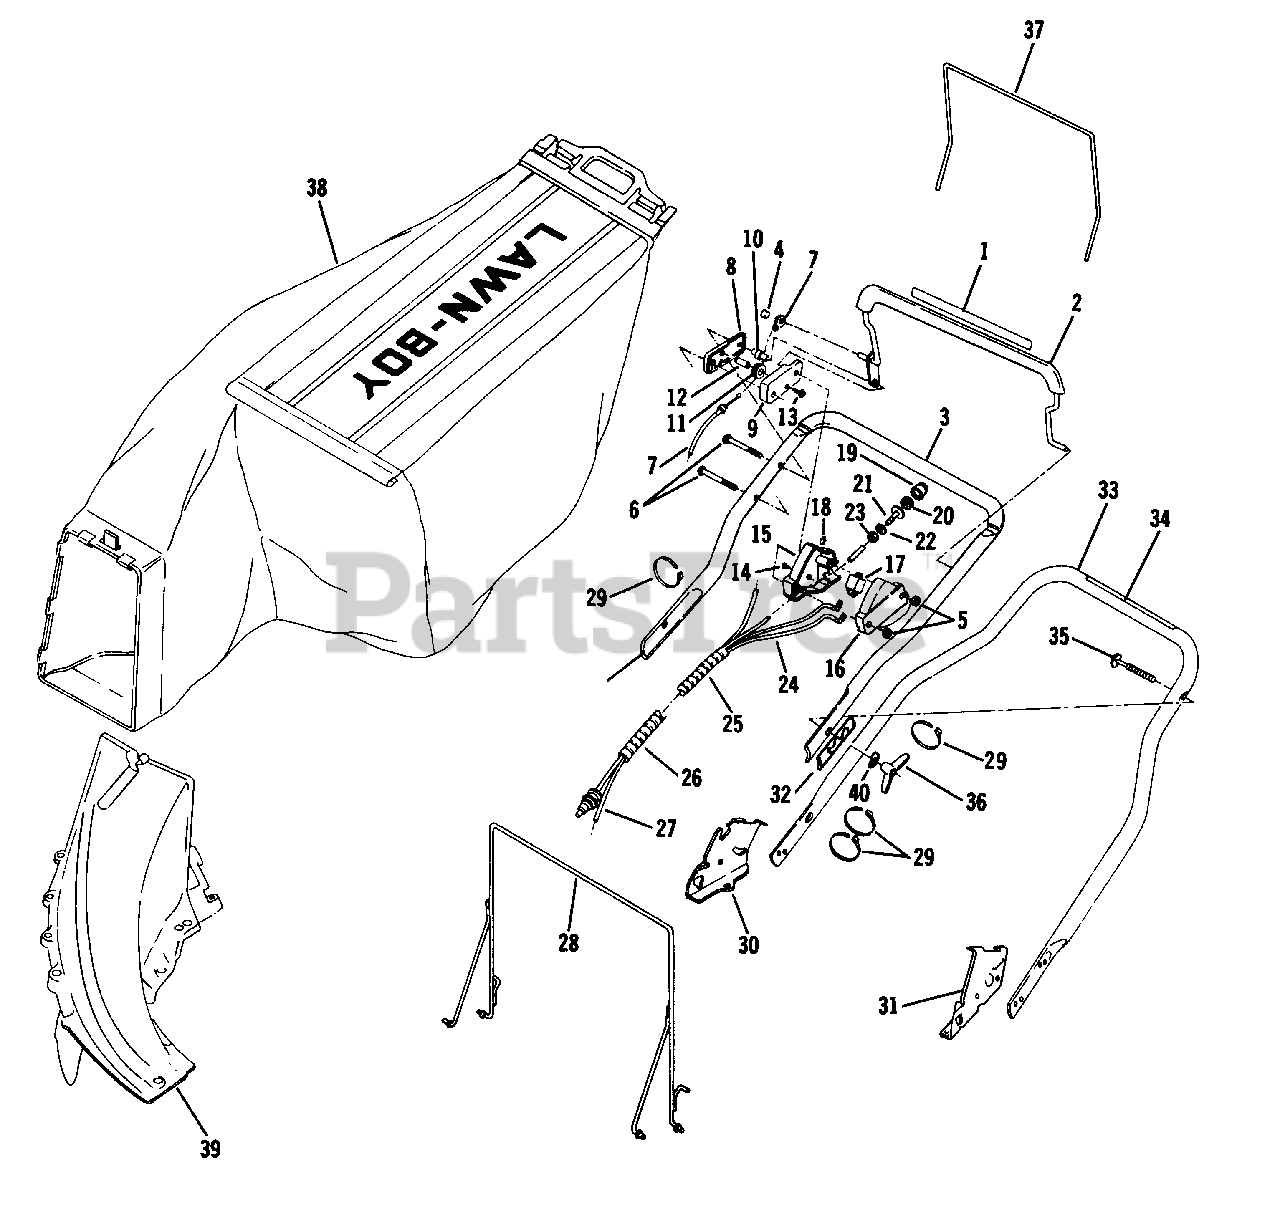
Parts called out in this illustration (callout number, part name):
1	Decal-Blade Control
2	Control Lever Assembly
3	Top Handle and Grip Assembly
4	Pushnut
5	Nut-Hex-Centerlock
6	Screw
7	Control Cable Assembly
8	Control Case-Outer
9	Control Case-Inner
10	Column
11	Pulley
12	Pin
13	Screw
14	Screw
15	Console-R.H.
16	Console-L.H.
17	Switch Assembly
18	Decal
19	Primer Bulb
20	Filter
21	Primer Base
22	Washer
23	Locknut
24	Wire Harness Assembly
25	Spiral Tubing
26	Spiral Tubing
27	Tubing
28	Hanger Assembly-Front
29	Tie Strap
30	Handle Bracket-R.H.
31	Handle Bracket-L.H.
32	Bracket
33	Handle-Bottom
34	Decal-Starting Inst.
35	Screw-Folding Handle
36	Knob
37	Hanger
38	Bag Assembly
39	Chute Assembly
40	Washer
